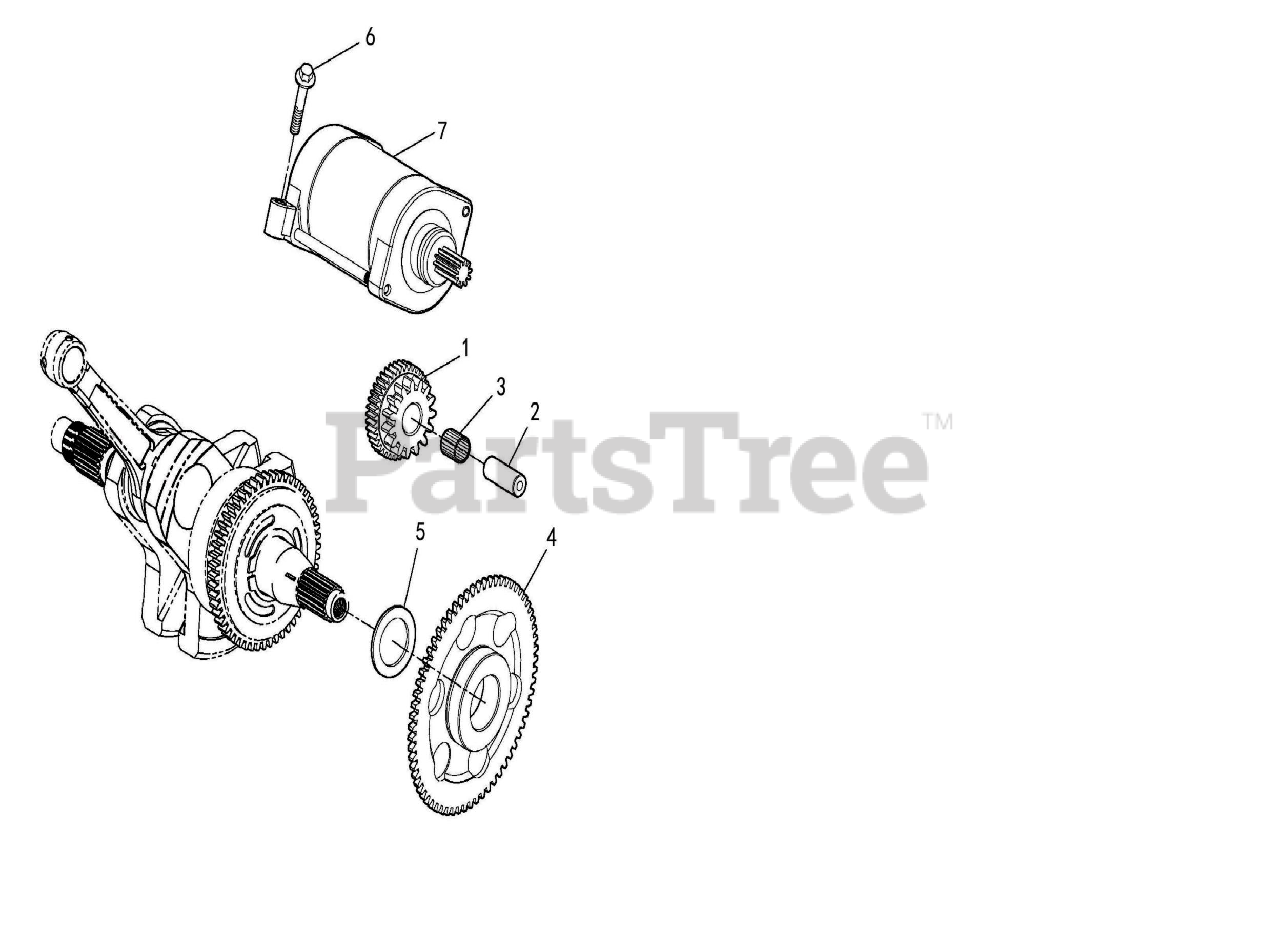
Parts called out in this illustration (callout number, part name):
1	Duplicate Gear
2	Duplicate Gear Shaft
3	Needle Bearing KBK121618
4	Disk Gear Assy
5	Washer 25X39X1
6	Hex flange bolts M6X30
7	STARTER ASSEMBLY
